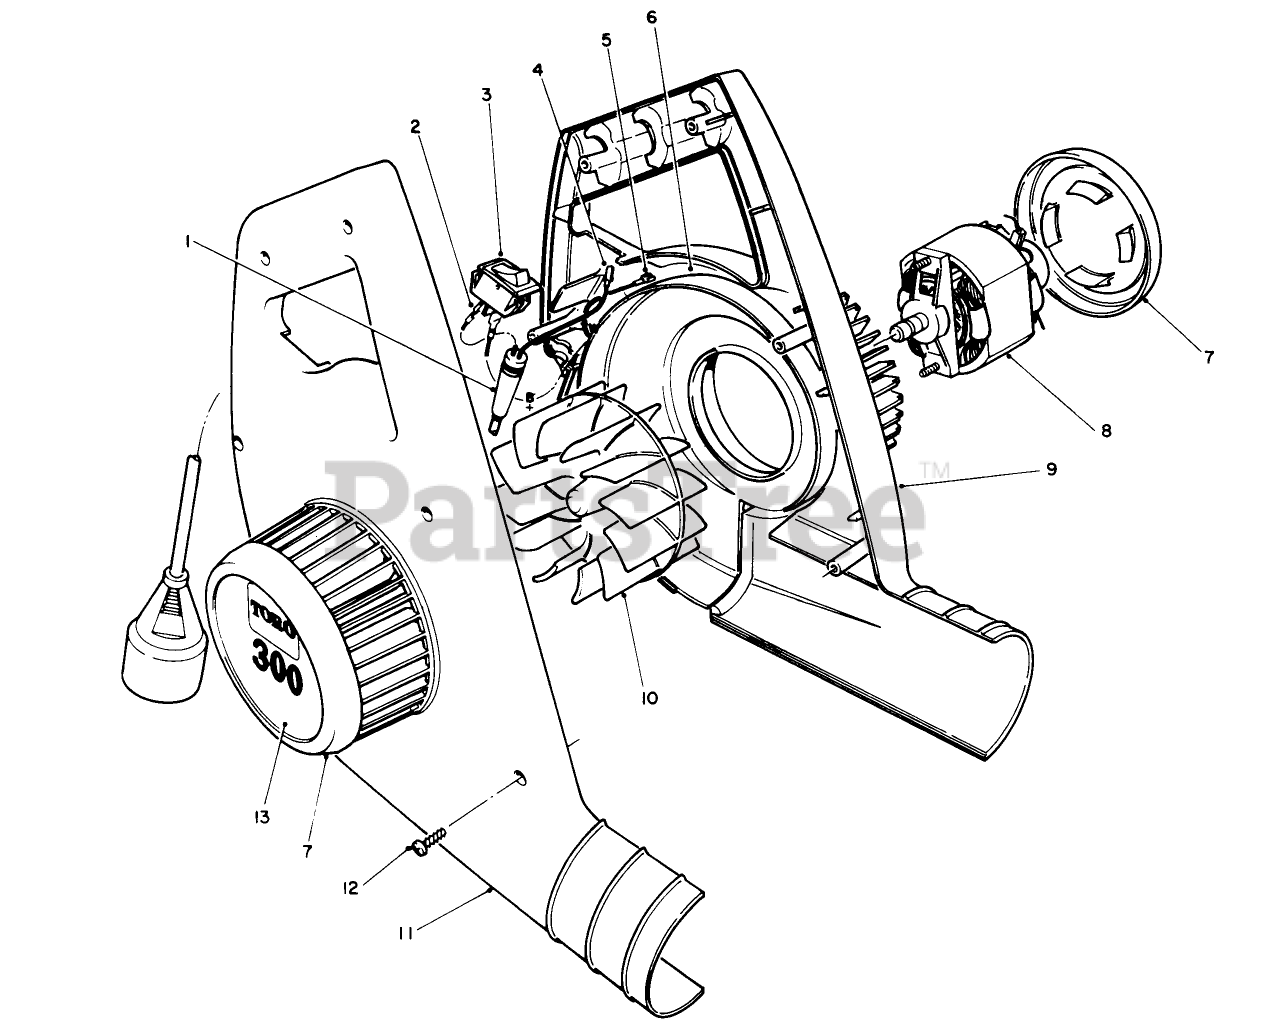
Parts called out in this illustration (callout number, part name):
1	Cord-Power Supply
2	TERMINAL- 1/4", XFORMER
3	ROCKER SWITCH W/LETTERS
4	MALE COUPLER
5	FEMALE COUPLER
6	MOTOR CVR,300 BLWR(120V
7	MINI BV-INTAKE COVER
8	MOTOR, 120V MINI-BLOWER
9	Housing-L.H.
10	MINI BL-IMPELLER
11	HOUSING,RH,MINI-BLOWER
12	Screw
13	COVER - LABEL
